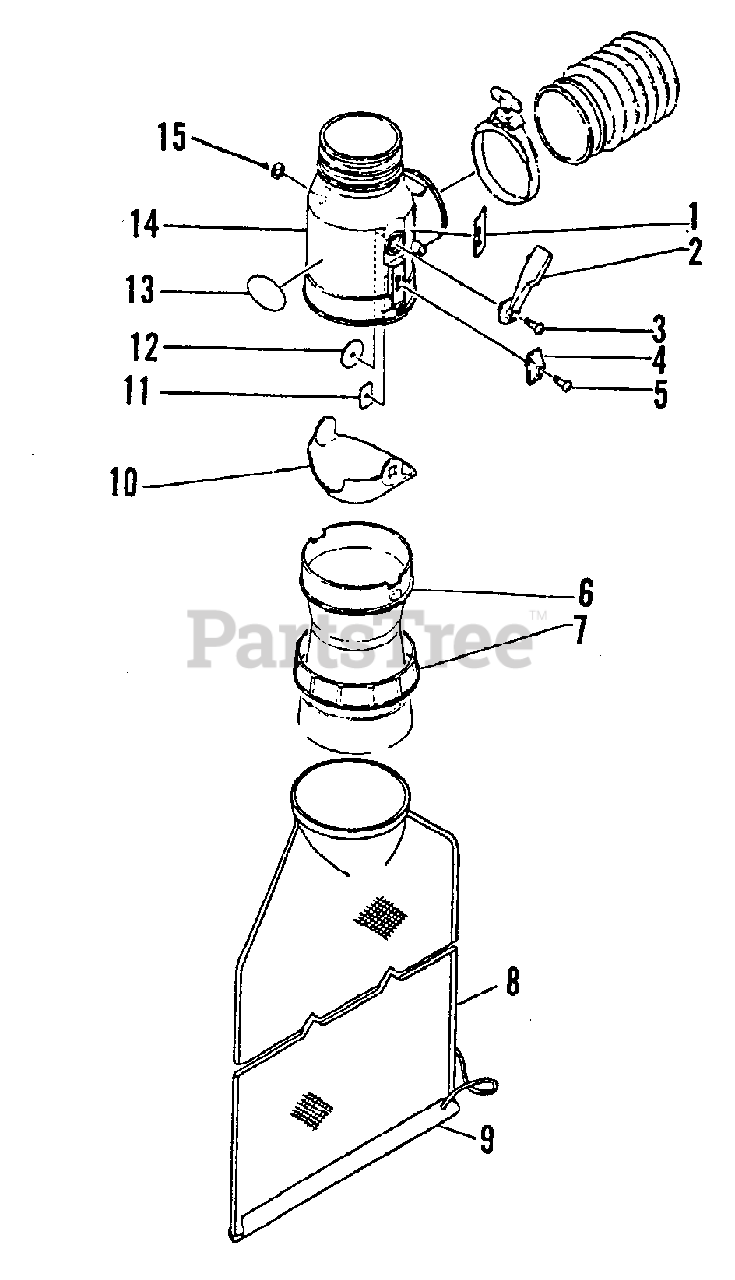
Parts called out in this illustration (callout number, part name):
1	LABEL - FUNCTION
3	SCREW - 5X14
5	SCREW - 4X14
6	CONNECTOR
8	BAG, DEBRIS
9	CLIP, VACUUM BAG
13	LABEL - ECHO
14	TUBE, SUCTION
15	RING, RETAINING - 8
